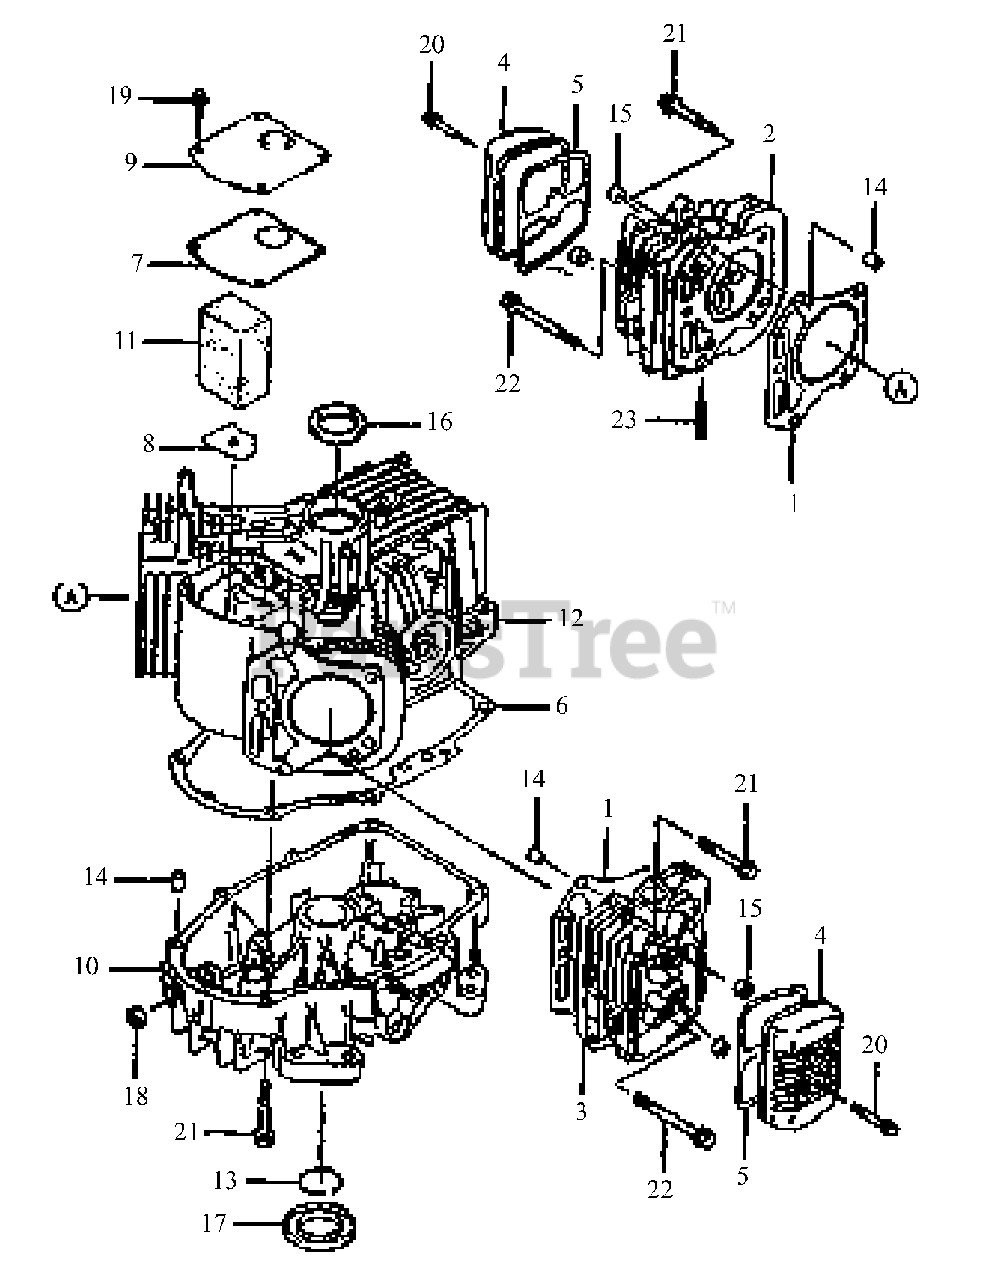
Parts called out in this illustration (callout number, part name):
2	Head, Cylinder #1
3	Head, Cylinder #2
5	Gasket, Rocker Case
6	Gasket, Crankcase
7	Gasket, Breather
9	Cover, Breather
10	Cover, Crankcase
11	Element, Breather
12	Crankcase, Comp.
15	Seal, Oil
19	Bolt, Flange
20	Bolt, Flange
21	Bolt, Flange
22	Bolt, Flange
